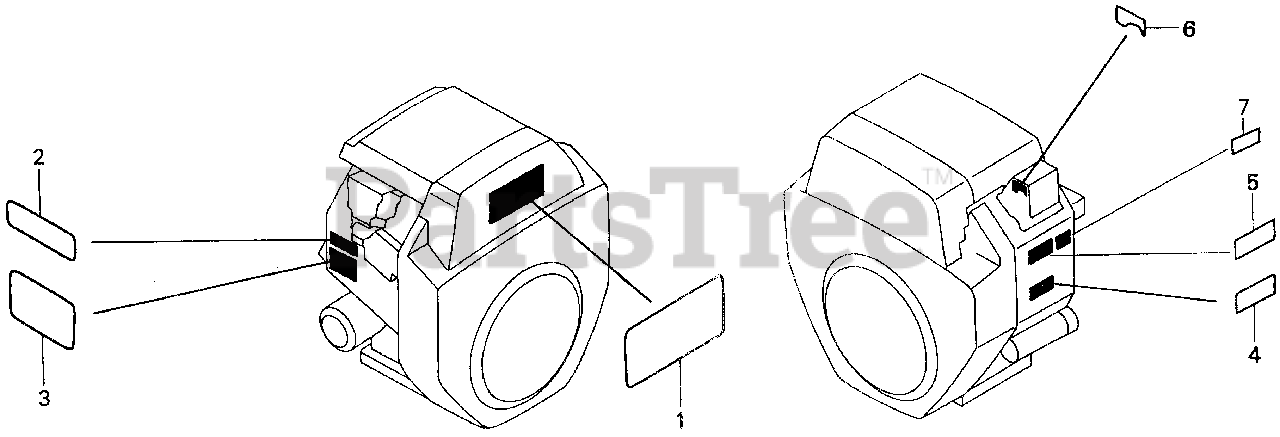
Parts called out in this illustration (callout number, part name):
1	MARK, EMBLEM (GX610)
2	LABEL, SPECIFICATION (GX610)
3	LABEL, CAUTION
7	LABEL, FUEL CAUTION
